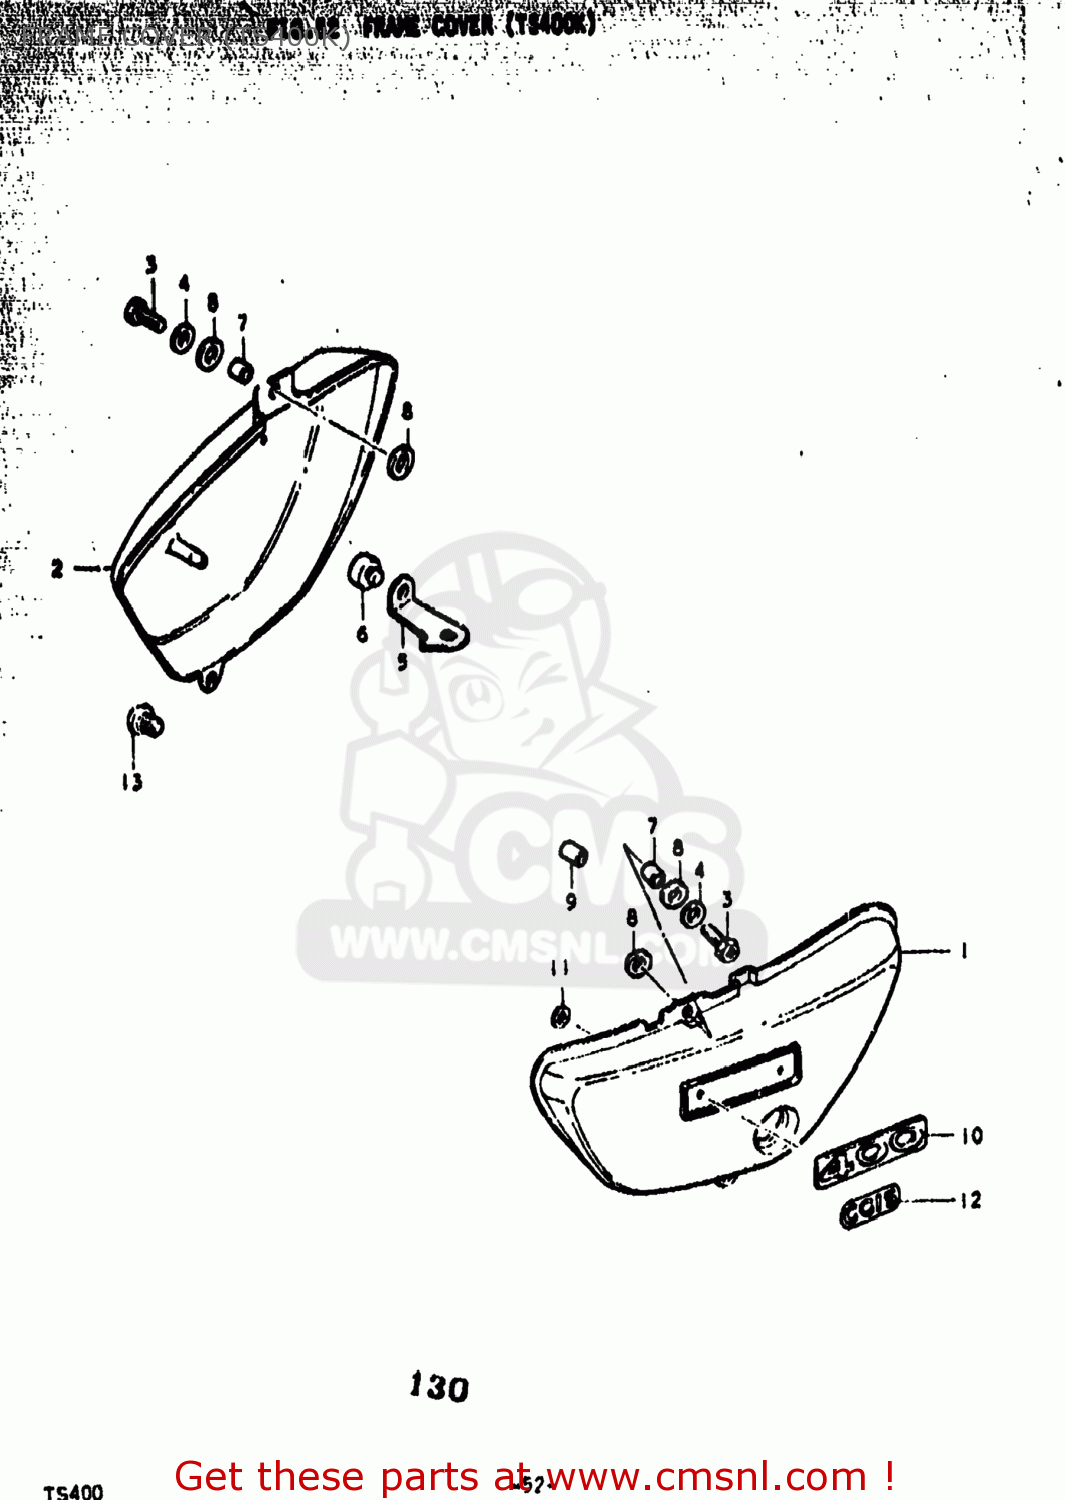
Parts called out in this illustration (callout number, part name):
1	COVER,FRAME,LEFT
2	COVER,FRAME,RIGHT
3	SCREW
4	WASHER
5	COVER
6	CUSHION
7	SPACER (6.1X8X9.5)
8	CUSHION
9	CUSHION
10	EMBLEM,FRAME COVER
11	NUT
12	EMBLEM,CCIS
13	CAP(OD:14)
